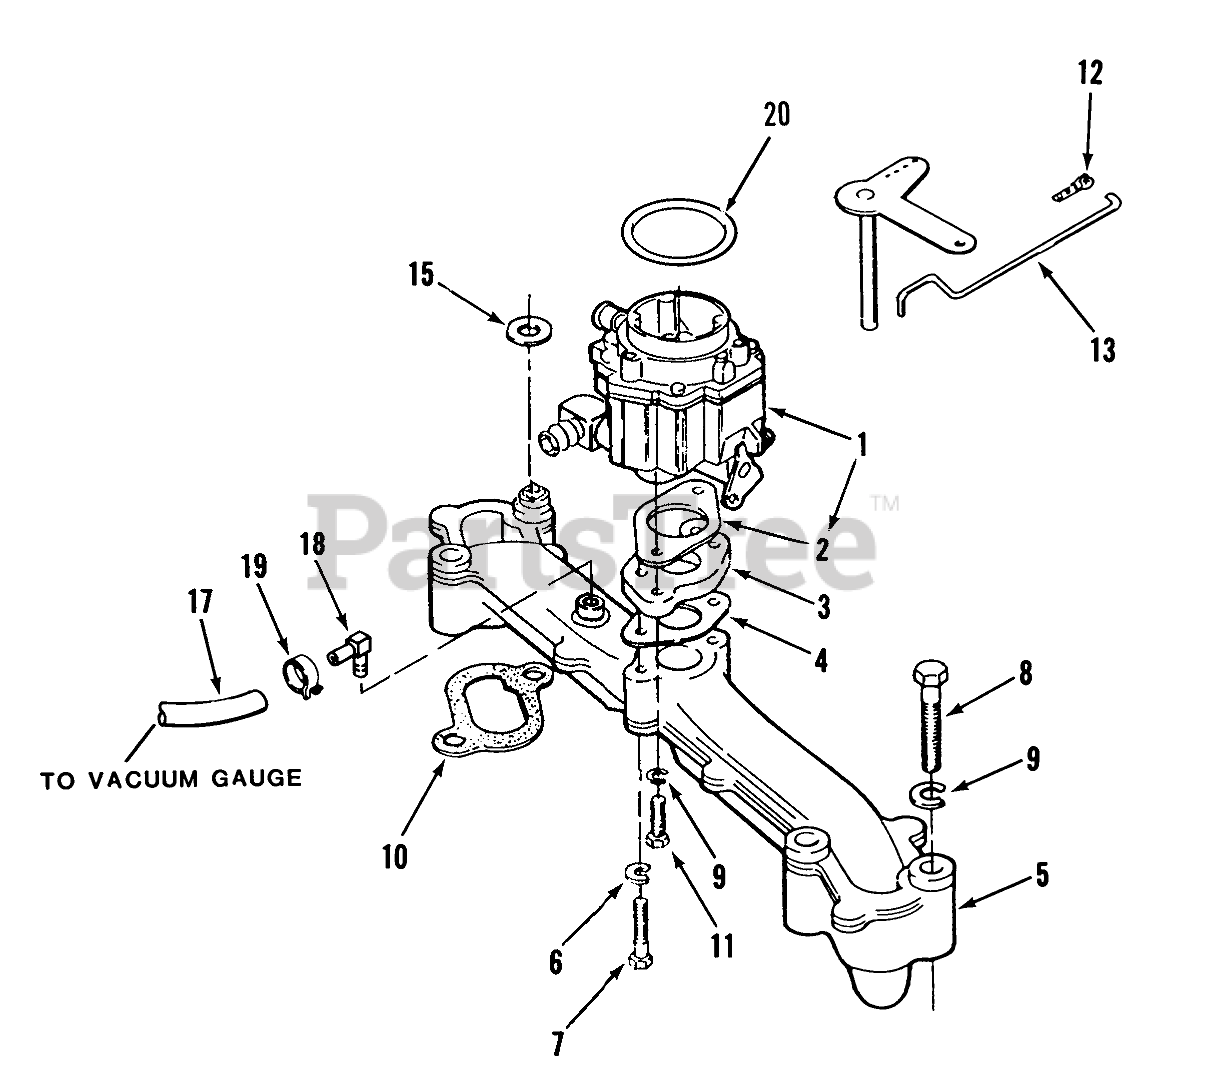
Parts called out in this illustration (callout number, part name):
1	Carburetor (includes mounting Gasket, Elbow and "O" Ring) see section 9-9 for complete carburetor breakdown 16 & 18HP
1	Carburetor (includes mounting Gasket, Elbow and "O" Ring) see section 9-9 for complete carburetor breakdown 20HP
2	Gasket
3	Fitting-Barbed
4	Gasket
5	Intake Manifold
5	Intake Manifold 518 & 520-H
6	Washer-Lock
7	Screw Hex Hd. 1/4-20 x 1-3/8
9	Washer
10	Gasket
11	HHCS 5/16-18 X 1
12	Retaining Clip
13	Governor Control Rod
15	FLAT WASHER
17	FUEL HOSE
18	Elbow Fitting
19	Clamp
